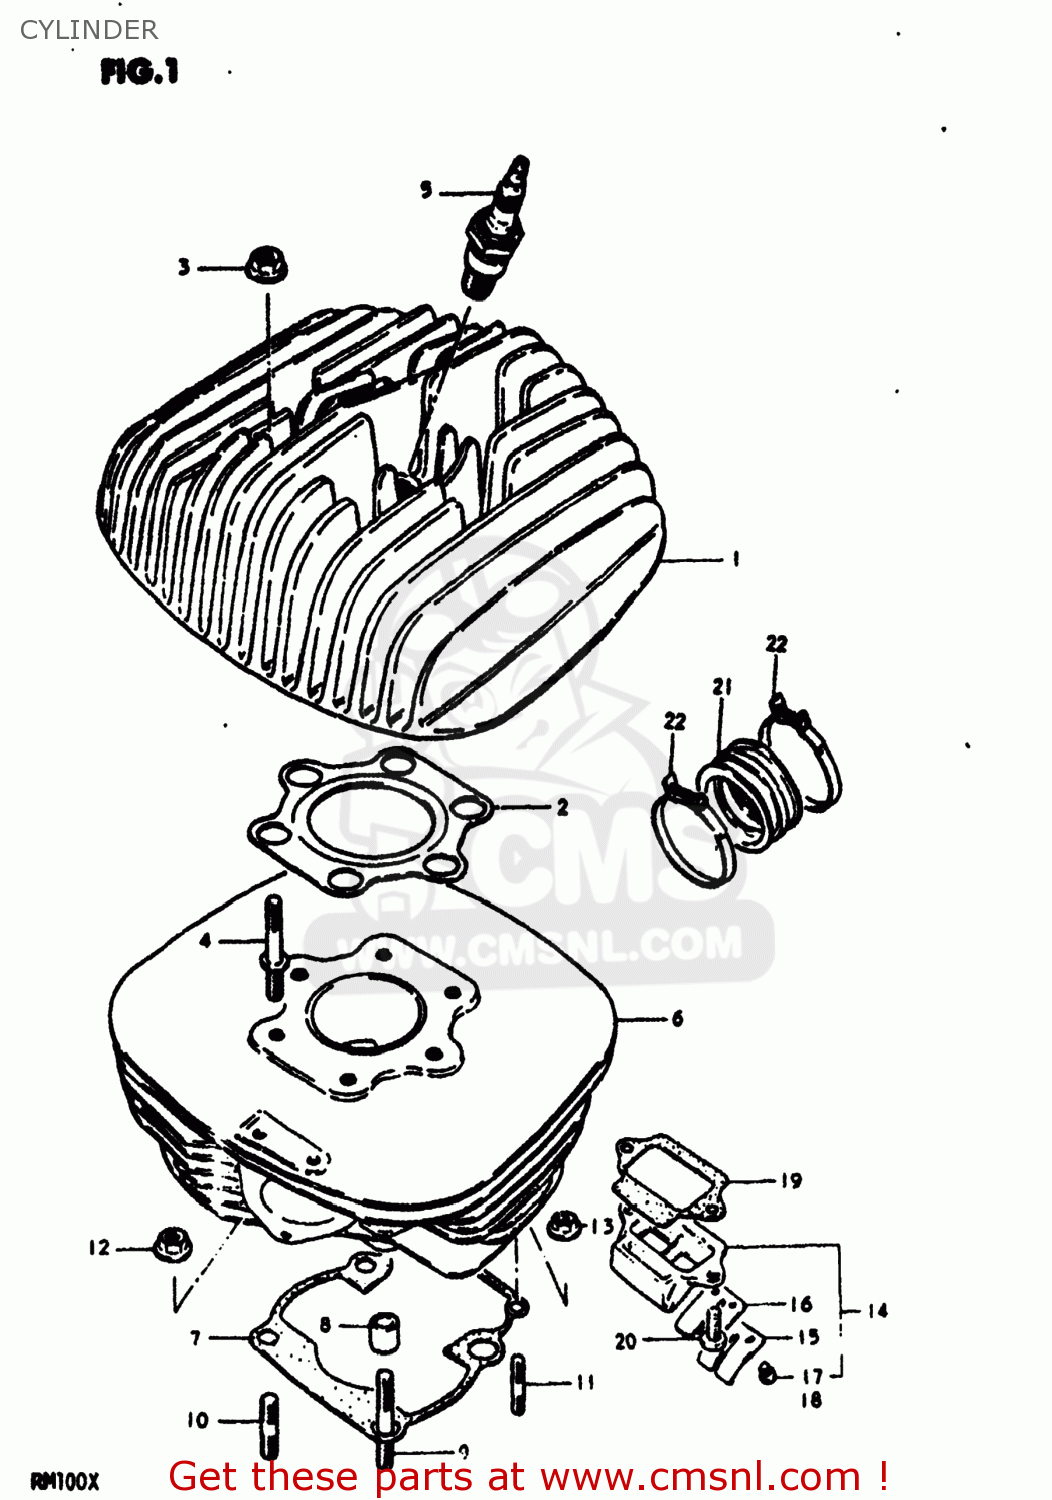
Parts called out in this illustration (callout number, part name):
1	HEAD,CYLINDER
2	GASKET,CYLINDER HEAD (NAS)
3	NUT
4	BOLT,STUD
5	SPARK PLUG
6	CYLINDER
7	GASKET,CYLINDER (MCA)
8	PIN
9	STUD 8X40
10	STUD 8X25
11	STUD 6X20
12	NUT
13	NUT
14	VALVE ASSY,REED
15	STOPPER,REED VALVE
16	VALVE,REED
17	SCREW
18	LOCK WASHER
19	GASKET,REED VALVE (MCA)
20	SCREW
21	PIPE,INTAKE
22	CLAMP
